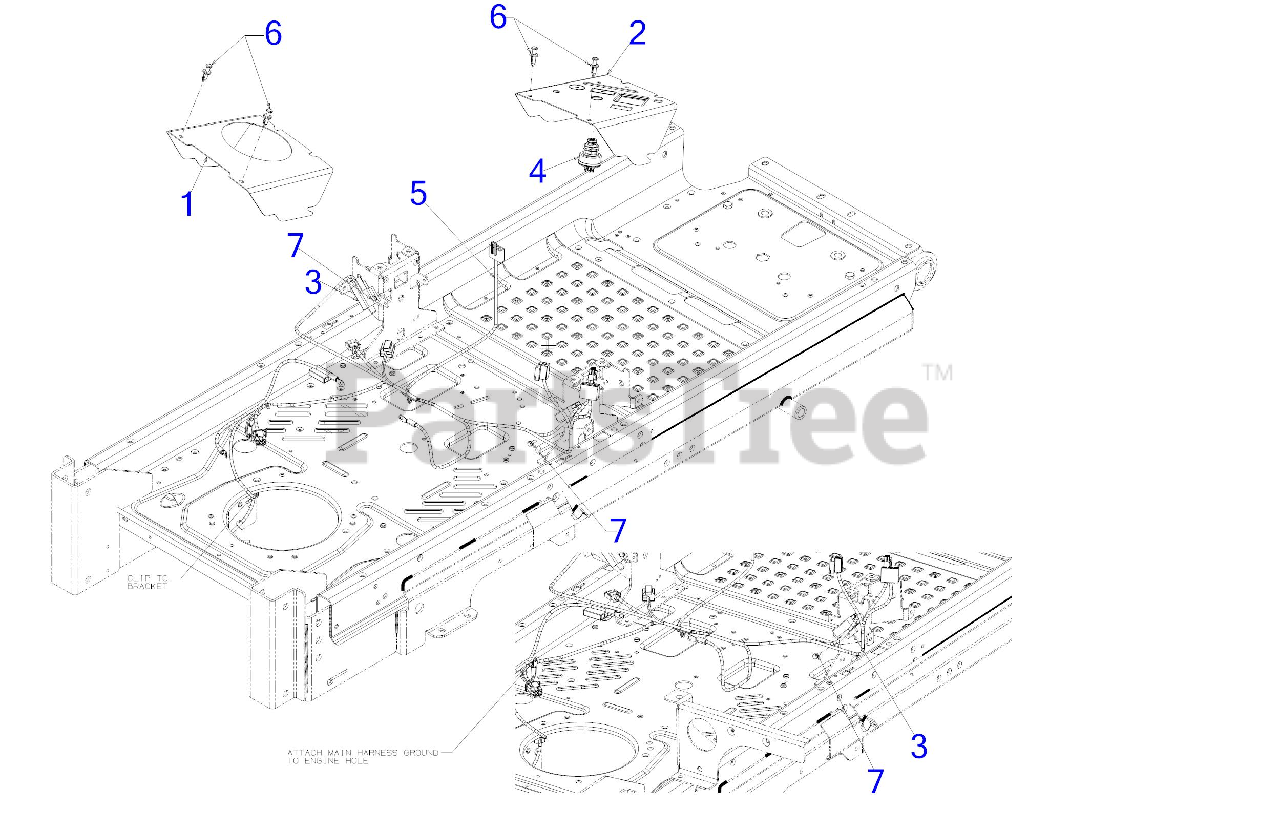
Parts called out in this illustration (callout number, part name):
2	CONSOLE COVER (RH)
3	INTERLOCK SWITCH (NO/NC)
4	KEY SWITCH (3 POSITION)
5	WIRING HARNESS
6	PLASTIC RIVET
7	SHOULDER SCREW
